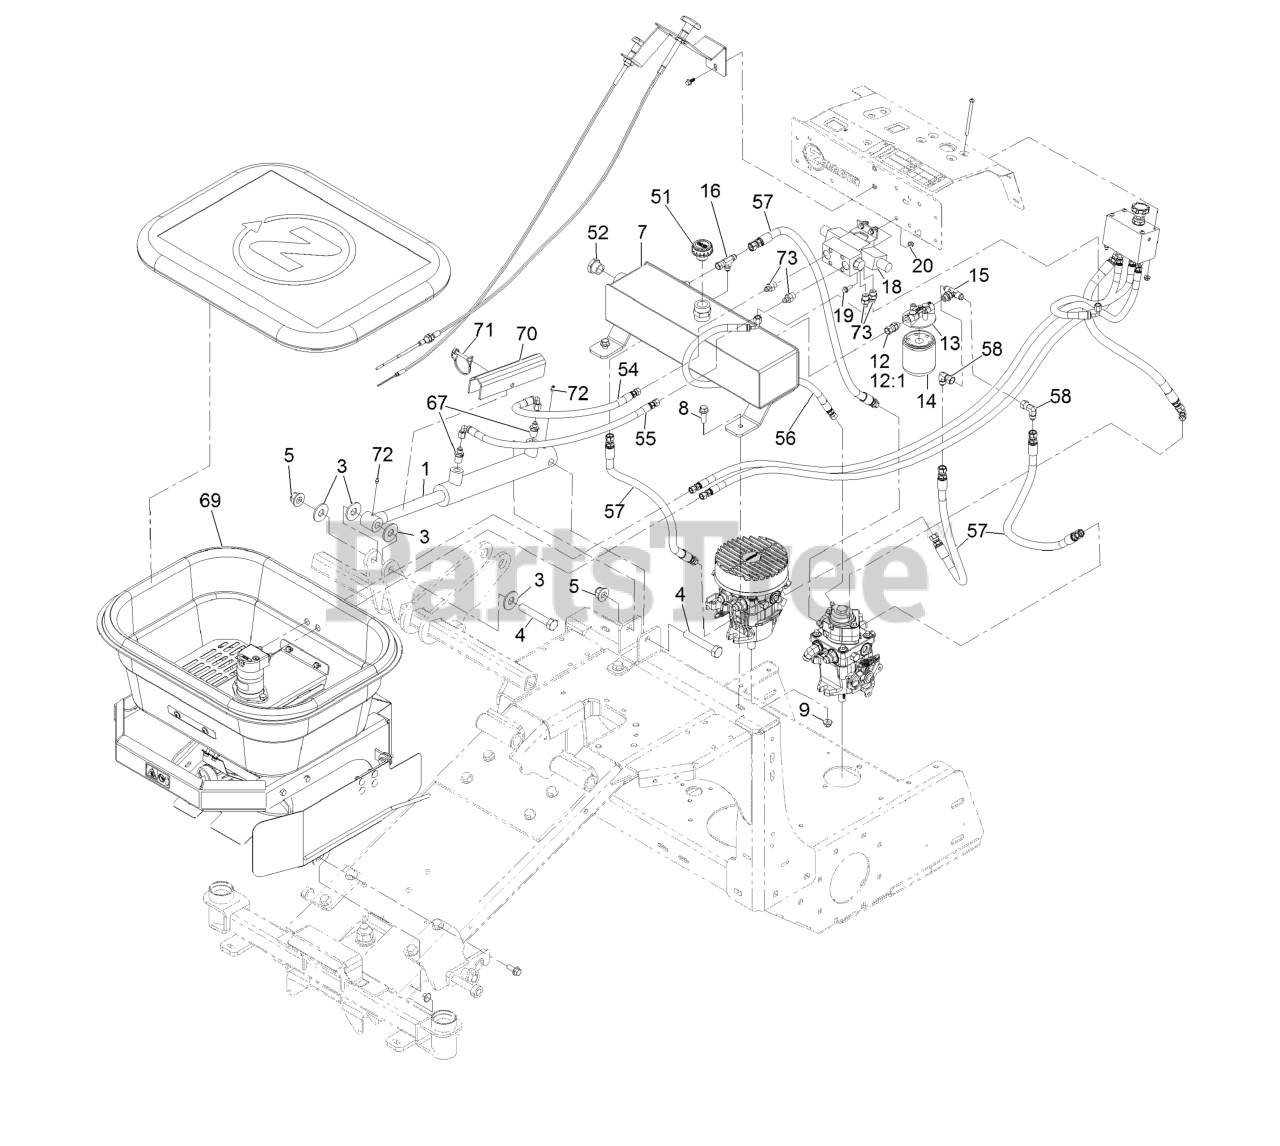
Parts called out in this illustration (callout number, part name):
1	LIFT CYLINDER NEW STYLE 8
3	WASHER-FLAT
4	SCREW-HH
5	Nut-Hex Flg 5/8-11 Nyloc
7	TANK-HYDRAULIC, ZPLUG
8	SCREW-HHF
9	NUT-HF, NI
12	6FJIC SWIVEL-6MORB
12:1	O-RING
13	HEAD-FILTER
14	FILTER-OIL, HYD
15	TEE-6MJIC-6MJIC-6MORB
16	FITTING-HYD, TEE
18	PARKER ELECTRIC ACTUATED
19	SCREW-HHF
51	HYDRAULIC TANK VENT CAP
52	FLUID SITE WINDOW
54	Hose ASM-HYD HP
55	Hose ASM-HYD HP
56	Hose ASM-HYD HP
57	HOSE-24,3/8,100R6,6FJIC,6
58	ELBOW-SWIVEL, 90 DEG
67	FITTING-STR
70	STOP-CYLINDER
71	PIN-HITCH
72	FITTING-GREASE
